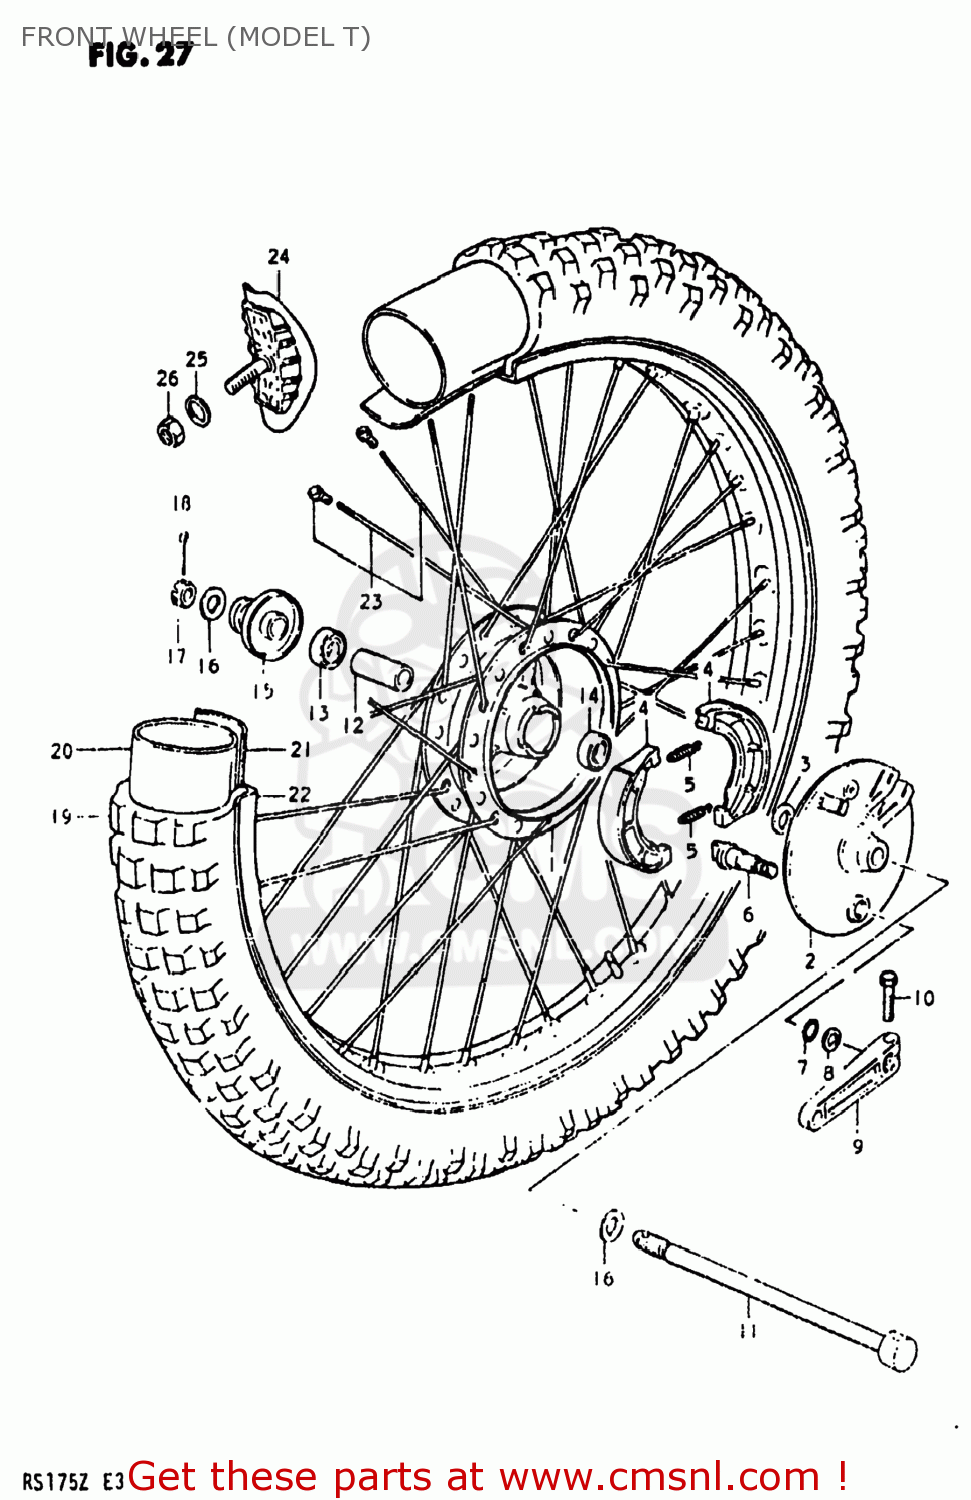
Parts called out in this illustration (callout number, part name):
1	HUB,FRONT
2	PANEL,FRONT HUB
3	BOSS
4	SHOE,BRAKE
5	SPRING(L:34)
6	CAM,FRONT BRAKE
7	O RING(D:2.5,ID:11.4)
8	WASHER(12.5X20X1)
9	LEVER,FRONT BRAKE CAM
10	BOLT
11	AXLE,FRONT
12	SPACER (12.6X19X52)
13	BEARING, RH
14	BEARING
15	SPACER,FRONT AXLE,RIGHT
16	WASHER
17	NUT, REAR AXLE
18	COTTER PIN
19	TIRE,FRONT
20	TUBE
21	PROTECTOR,WHEEL,INNER
22	RIM,FRONT WHEEL (1.60X21)(
23	SPOKE SET,FRONT
24	STOPPER,BEAD
25	WASHER
26	NUT
